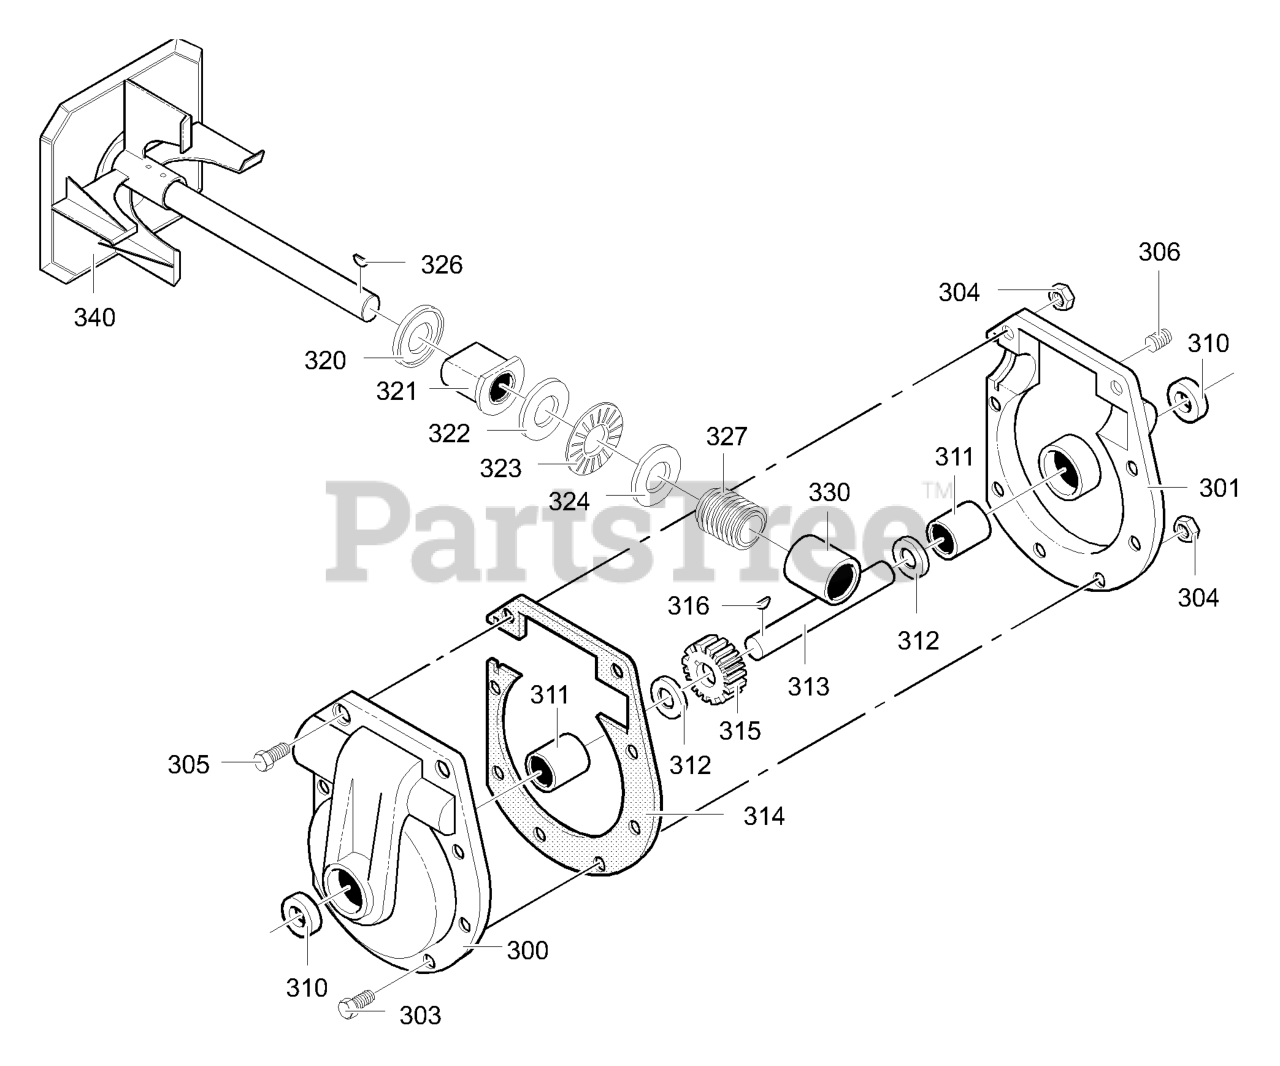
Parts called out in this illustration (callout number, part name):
300	CASE, GEAR, RH
301	CASE, GEAR, LH
303	SCREW, 5/16-24 x 1.00
304	NUT, 5/16-24
306	PIPE PLUG
310	SEAL, OIL
311	BEARING, SLEEVE
312	WASHER, FLAT 1.00 x 1.54 x .09
313	SHAFT, AUGER OUTPUT
314	GASKET, GEAR BOX
315	WORM GEAR
316	KEY, WOODRUFF #91
320	RING, QUAD
321	BEARING, FL
322	WASHER, FLAT
323	BEARING, ROLL
324	WASHER, FLAT
327	WORM GEAR
330	BEARING, SLEEVE
